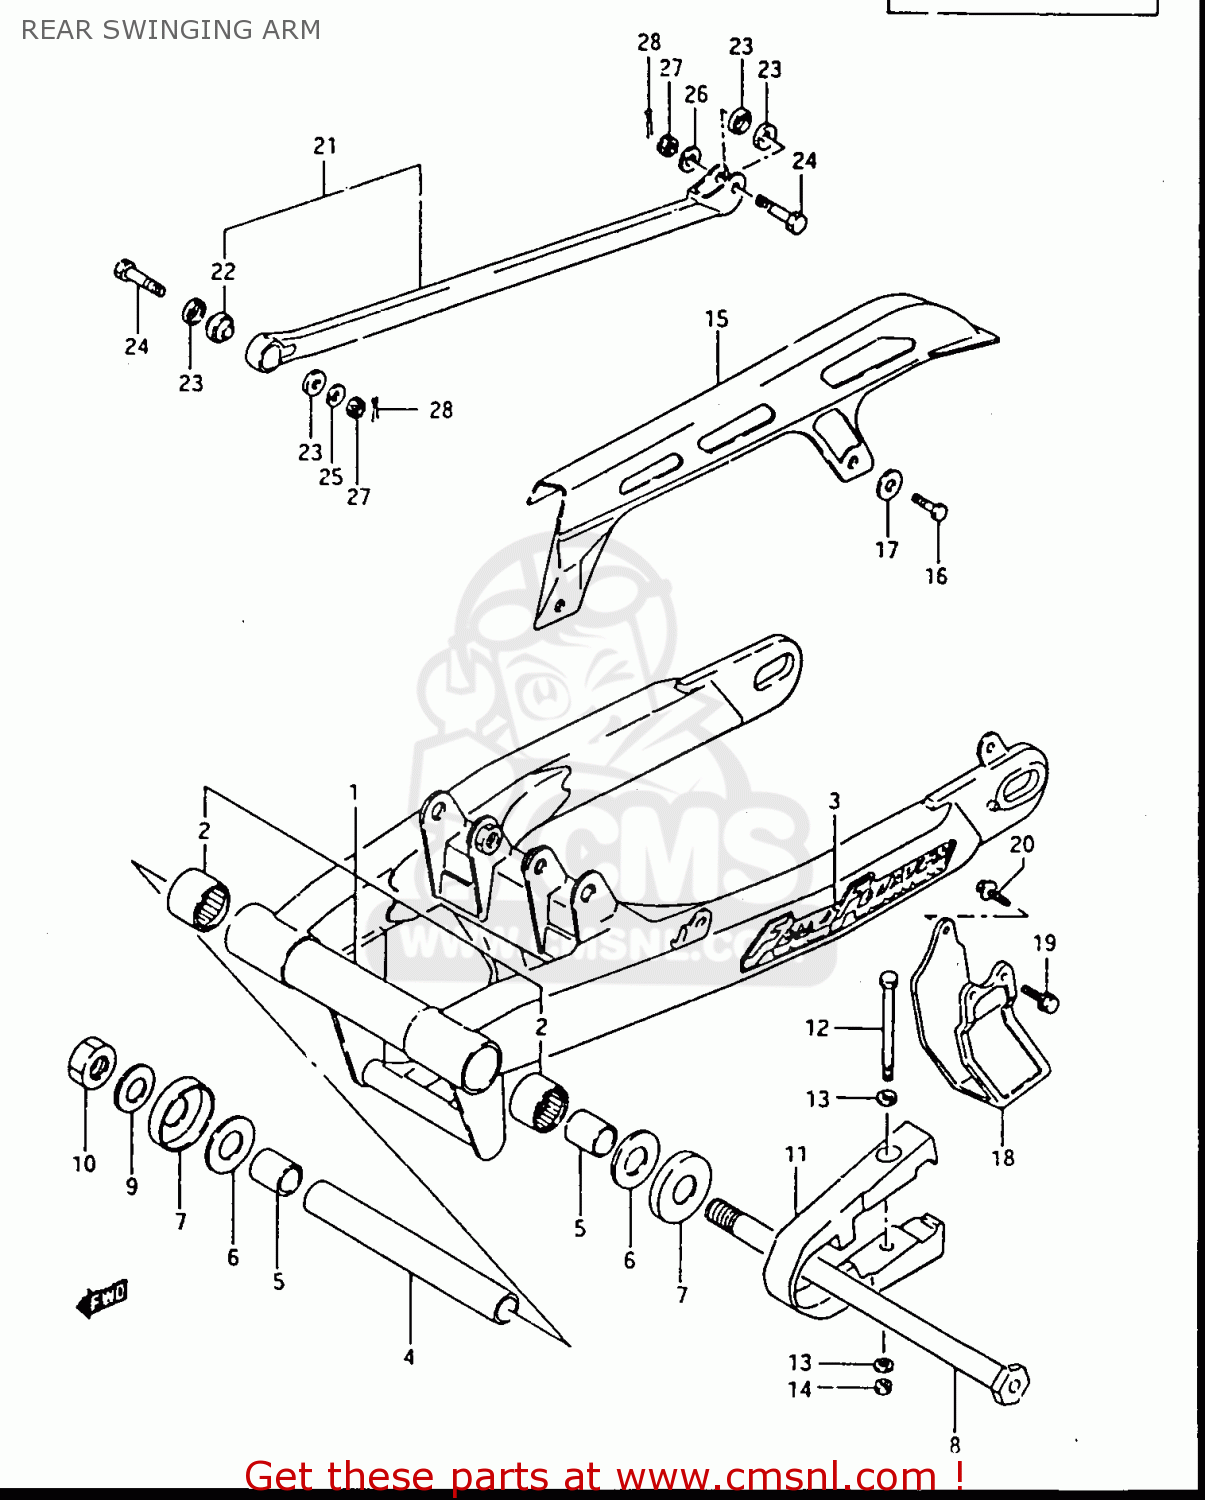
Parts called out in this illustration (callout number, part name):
1	SWINGING ARM ASSY, REAR
2	BEARING(22X29X20)
3	EMBLEM
4	SPACER,RR SWGARM PIVOT CTR
5	SPACER,RR SWGARM PIVOT
6	WASHER
7	SEAL,RR SWGARM PIVOT DUST
8	SHAFT,RR SWINGINGARM PIVOT
9	WASHER
10	NUT 16MM
11	BUFFER,CHAIN TOUCH DEFENSE
12	BOLT,TOUCH DEFENSE FTG
13	WASHER(5.2X16X1)
14	NUT
15	CASE,CHAIN
16	BOLT
17	WASHER
18	GUIDE,CHAIN
19	BOLT
20	BOLT 6X16
21	LINK,REAR TORQUE
22	SPHERICAL BEARING,TORQUE
23	24
24	BOLT 8X32
25	WASHER
26	WASHER
27	NUT 8MM
28	PIN 20X20
